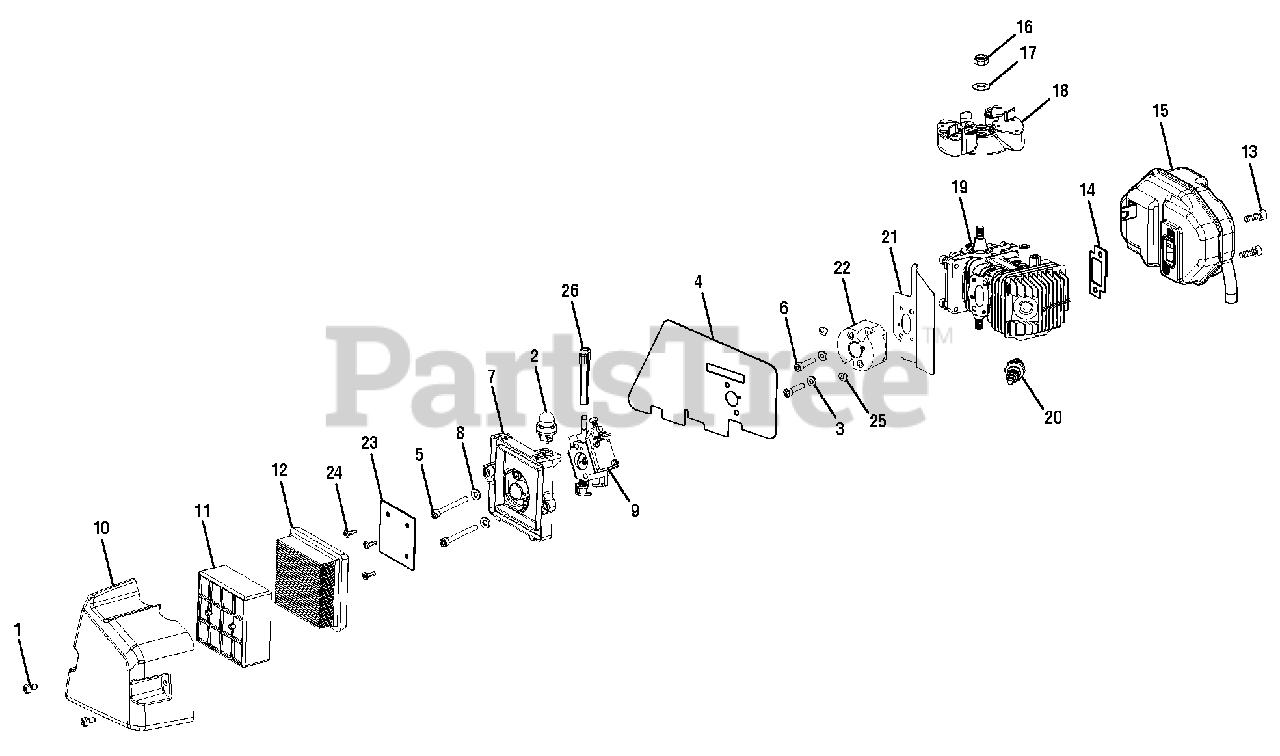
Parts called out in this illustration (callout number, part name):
1	Screw (M5, Special)
2	Primer Assembly
3	Spring Washer (M5)
5	Screw (M5 x 50 mm, Soc. Hd.)
6	Screw (M5 x 0.8 in.)
7	Air Box Base
8	Washer (ID5.8 x OD11.5 x 1.7t)
9	Carburetor (Inc. Key No. 26)
10	Air Box Cover
11	Air Filter Box
12	Air Filter
13	Bolt (1/4-20 x 18 mm)
15	Exhaust Assembly
16	Lock Nut (M8)
17	Washer (ID9 x OD17.7 x 1.1t)
18	Flywheel Assembly
19	Short Block Assembly
20	Spark Plug (RCJ4)
24	Screw (M4 x 12 mm, Pan Hd.)
25	Washer (Heat Dam)
26	Choke Lever
